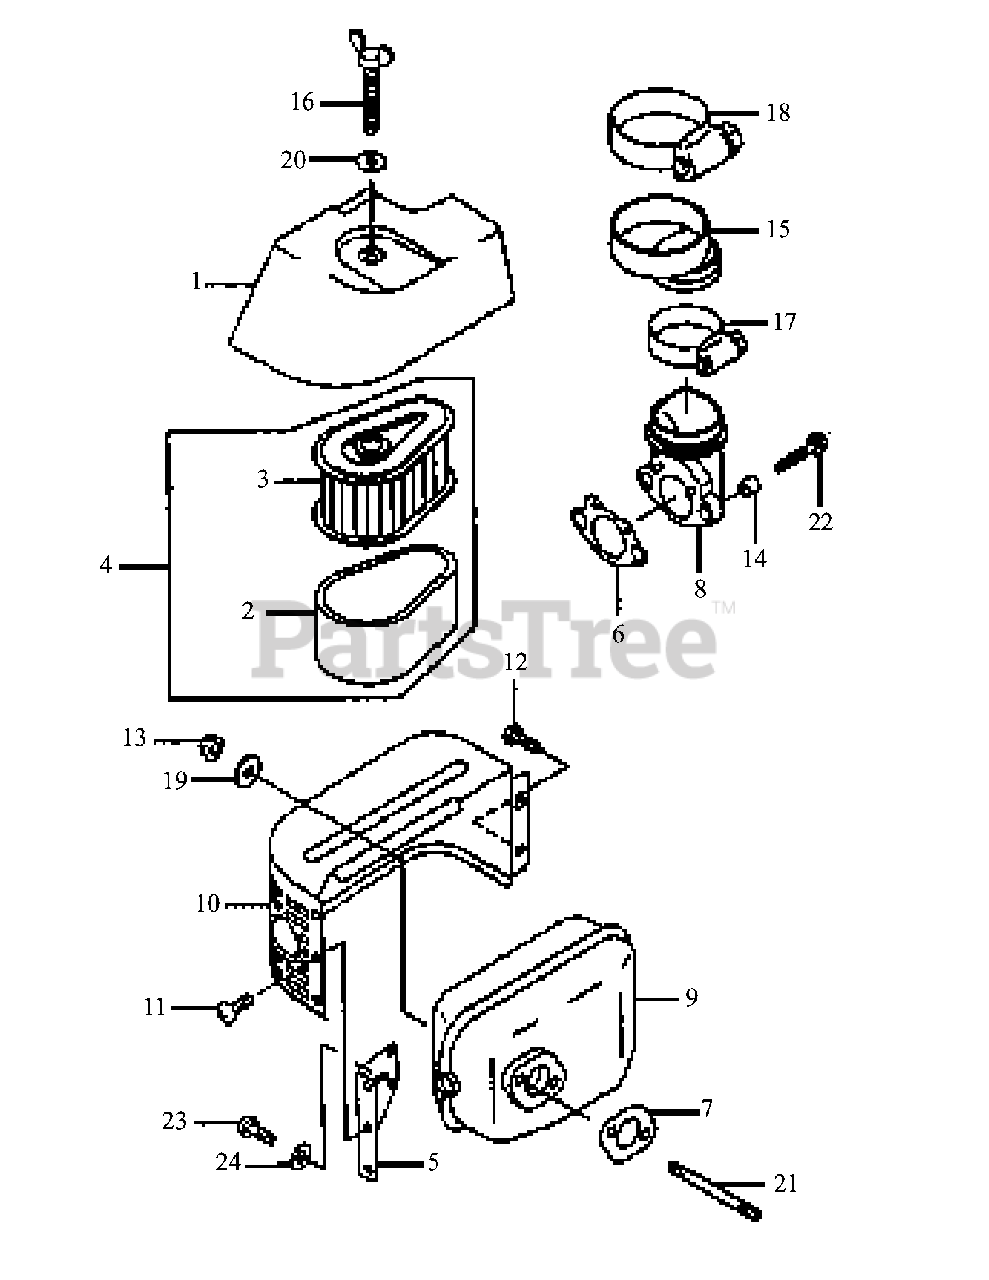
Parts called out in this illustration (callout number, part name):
1	Cap Air Filter
2	Element, Air Filter
3	Element, Air Filter
4	Element Assembly
6	Gasket, Intake Pipe
7	Gasket, Muffler
10	Cover, Muffler
14	Spacer 6.2x7.8x8
16	Bolt
17	Clamp
19	Washer, 7x21x2.3
20	Washer, 6.5x18x2.0
